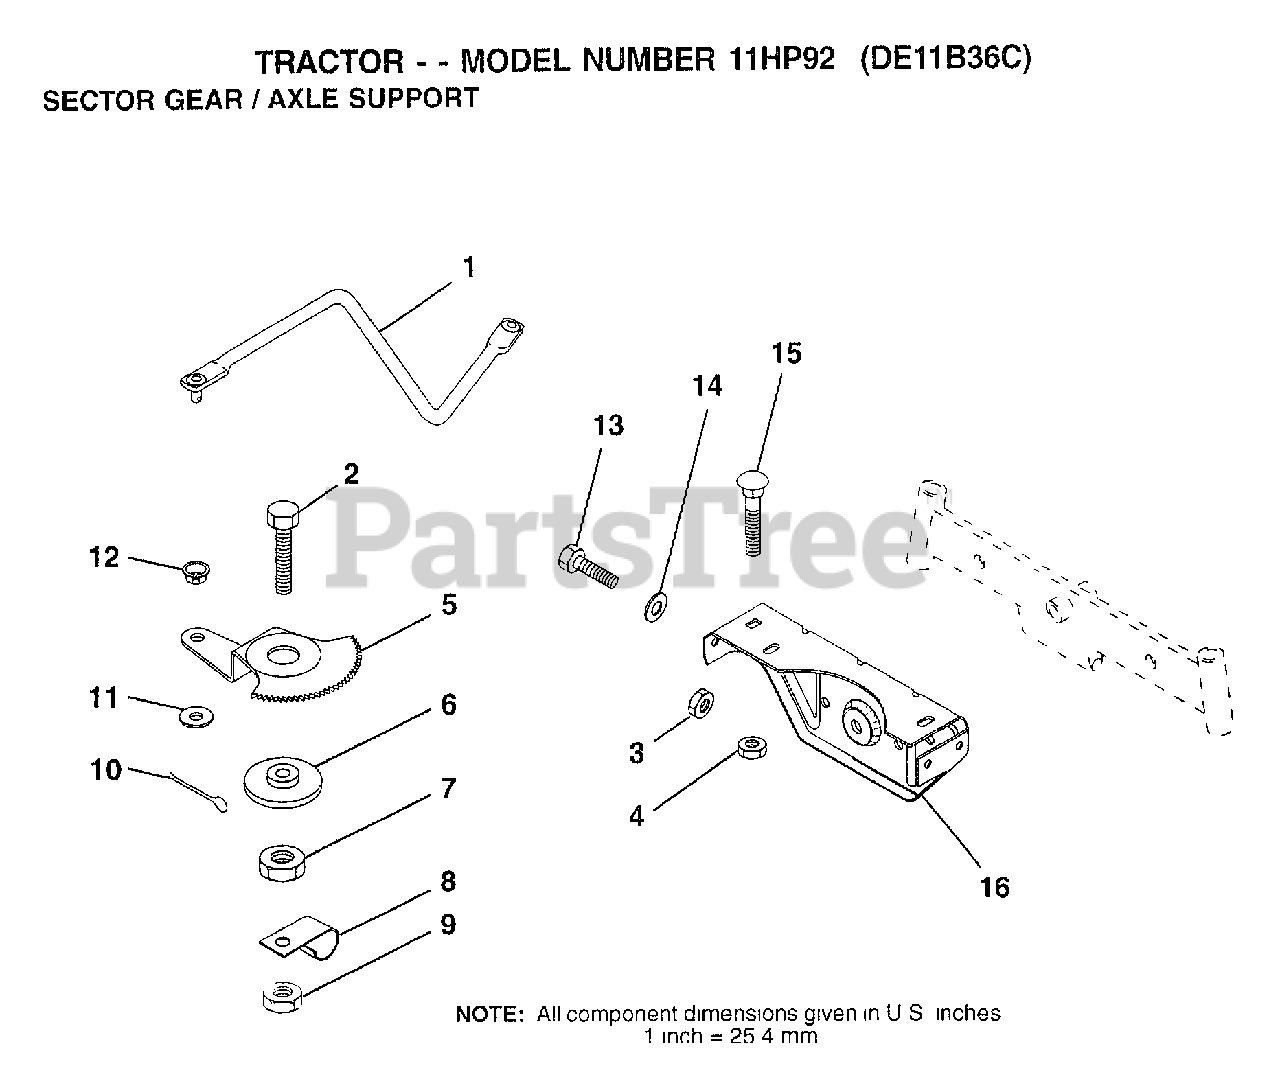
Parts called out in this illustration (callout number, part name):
1	DRAG LINK
2	"BOLT,HEX"
5	GEAR SECTOR
6	BUSHING
7	NUT
8	CLIP INSULATOR
9	NUT LTV
10	COTTER PIN
11	WASHER
12	BUSHING.DRAGLINK
13	BOLT
14	WASHER
15	BOLT
16	SUPT AXLE FRONT
